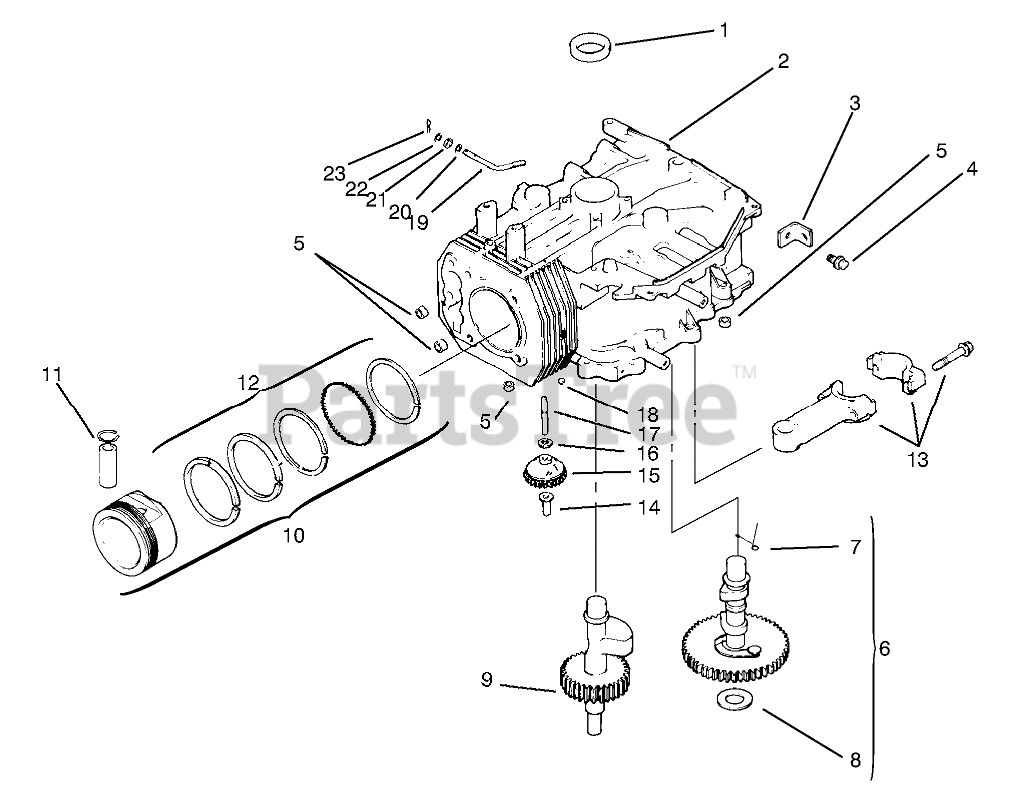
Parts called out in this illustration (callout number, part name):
1	Seal-Crankshaft
2	Block-Short
3	Strap-Lifting
4	Screw
5	Pin-Dowel
6	Camshaft Assembly
7	Spring-Actuating
8	Shim-Camshaft
9	Shaft-Balance
10	Piston ASM STD Incl 11-2
10	Piston ASM .25 Incl 11-2
10	Piston ASM .50 Incl 11-2
11	Retainer-Piston Pin
12	Ring Set STD
12	Ring Set .25
12	Ring Set .50
13	Rod Connecting STD
13	Rod Connecting .25
14	Pin-Governor
15	Gear, governor
16	Washer
17	Shaft-Gear, Governor
18	Plug
19	Kit-Governor Cross
20	Washer, plain 6 mm
21	Seal-Cross Shaft
22	Washer
23	Clip-Hitch Pin
